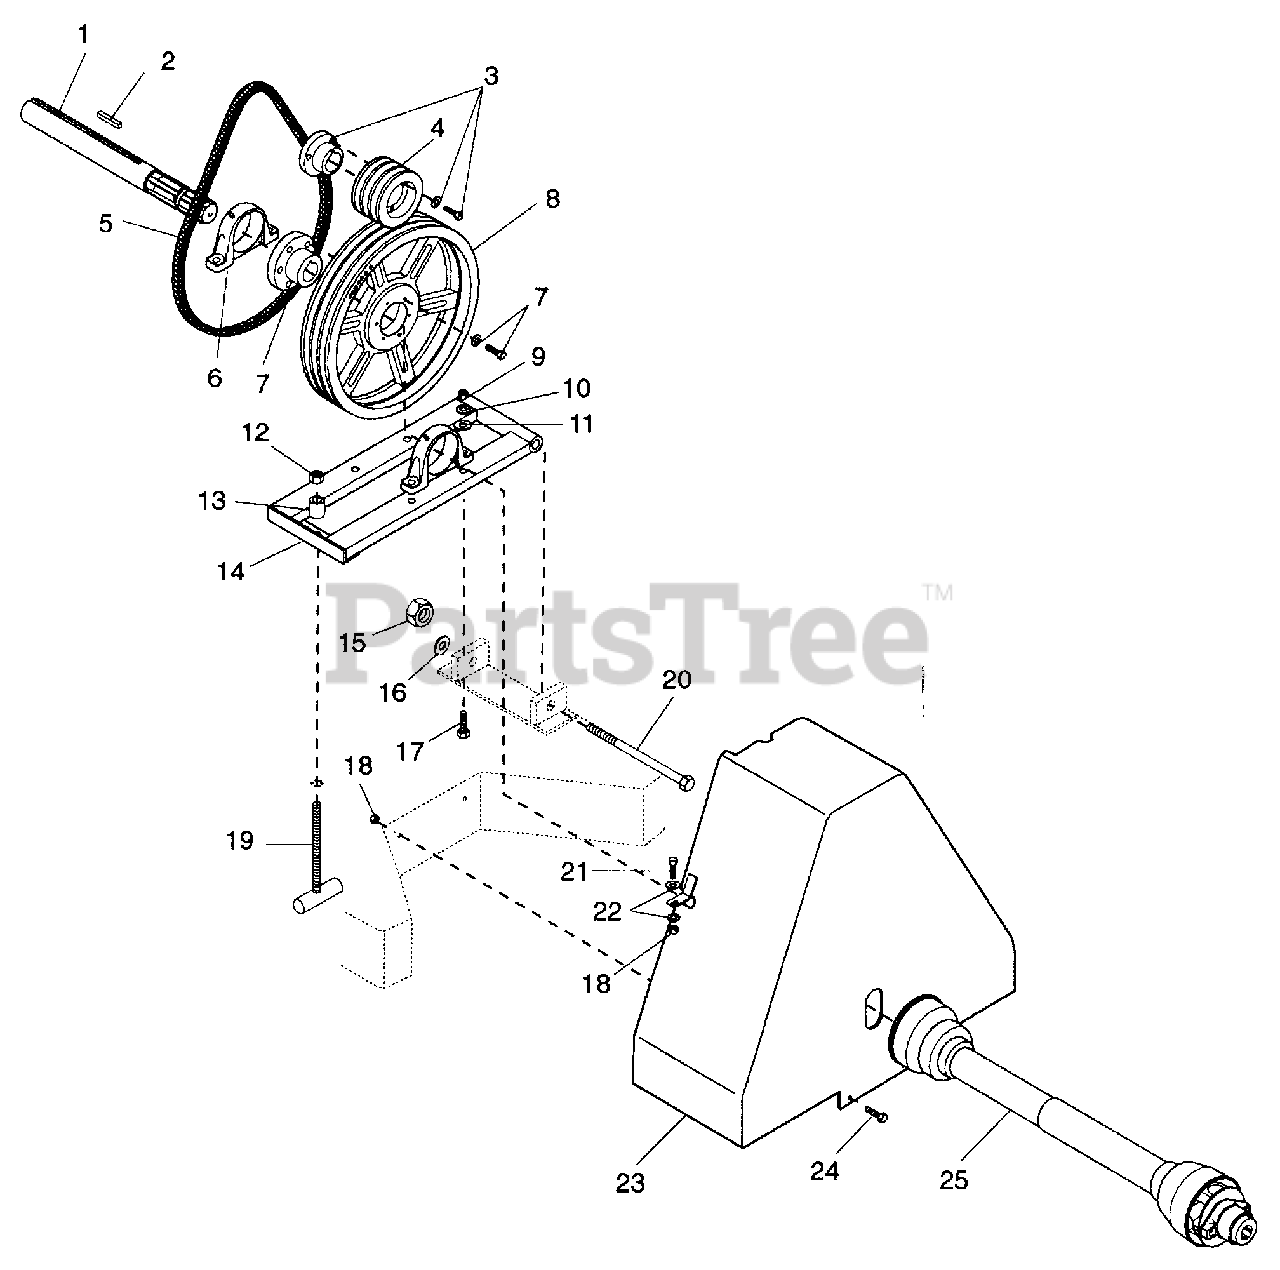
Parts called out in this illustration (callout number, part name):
1	PTO Jack Shaft
2	Key-Straight .38 x 2.0 x .38
3	Bushing
4	Pulley-Browning 384.2 Slotted Head
5	V-Belt B54
6	Bearing-Pillow-Block 1.500 x 2 Bolt x 2.344
7	Bushing SK x 1 1/2
8	Pulley-Browning 3815.45 SK
9	Nut .50-13
10	Washer-Lock .500 x .151
11	Washer-Flat-Steel .531 x 1.250 x .100
12	Nut-Locking-Nylon .625-11 Grade 2
13	Adjuster Spacer
14	Swing Arm Weldment
15	Nut-Locking Flex 1.0-8
16	Washer-Flat-Steel 1.010 x 1.505 x .062
17	Bolt-Hex .50-13 x 2.75 Grade 5
18	Nut-Locking-Nylon .312-18 w/Insert Grade 2
19	Threaded T Handle
20	Bolt-Hex 1-8 x 11 Grade 8
21	Bolt-Hex .31-18 x 1.00 Grade 5
22	Washer-Flat-Steel .38 x .875 x .083
23	Belt Guard Weldment
24	Bolt-Hex .31-18 x .75 Grade 5
25	Pillow - PTO Kit For 941005
